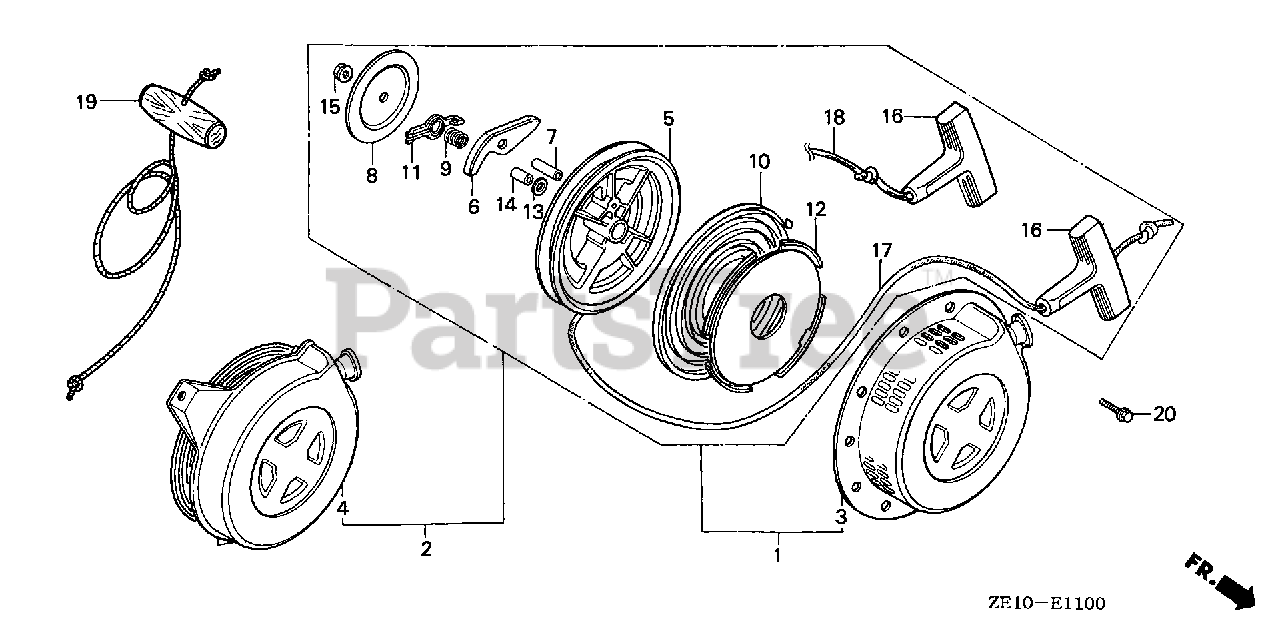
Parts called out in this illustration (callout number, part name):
1	STARTER ASSY., RECOIL *R8* (BRIGHT RED)
3	CASE, RECOIL STARTER *R8* (BRIGHT RED)
5	PULLEY, RECOIL STARTER
6	RATCHET, STARTER
7	PIN, STARTER RATCHET
8	PLATE, FRICTION
9	SPRING, FRICTION
10	SPRING, RECOIL STARTER
11	GUIDE, RATCHET
12	CASE, RECOIL STARTER SPRING
13	WASHER, STARTER
14	SHAFT, SUB
16	KNOB, RECOIL STARTER
17	ROPE, RECOIL STARTER
20	BOLT, FLANGE (6X8)
20	BOLT, FLANGE (6X10)
